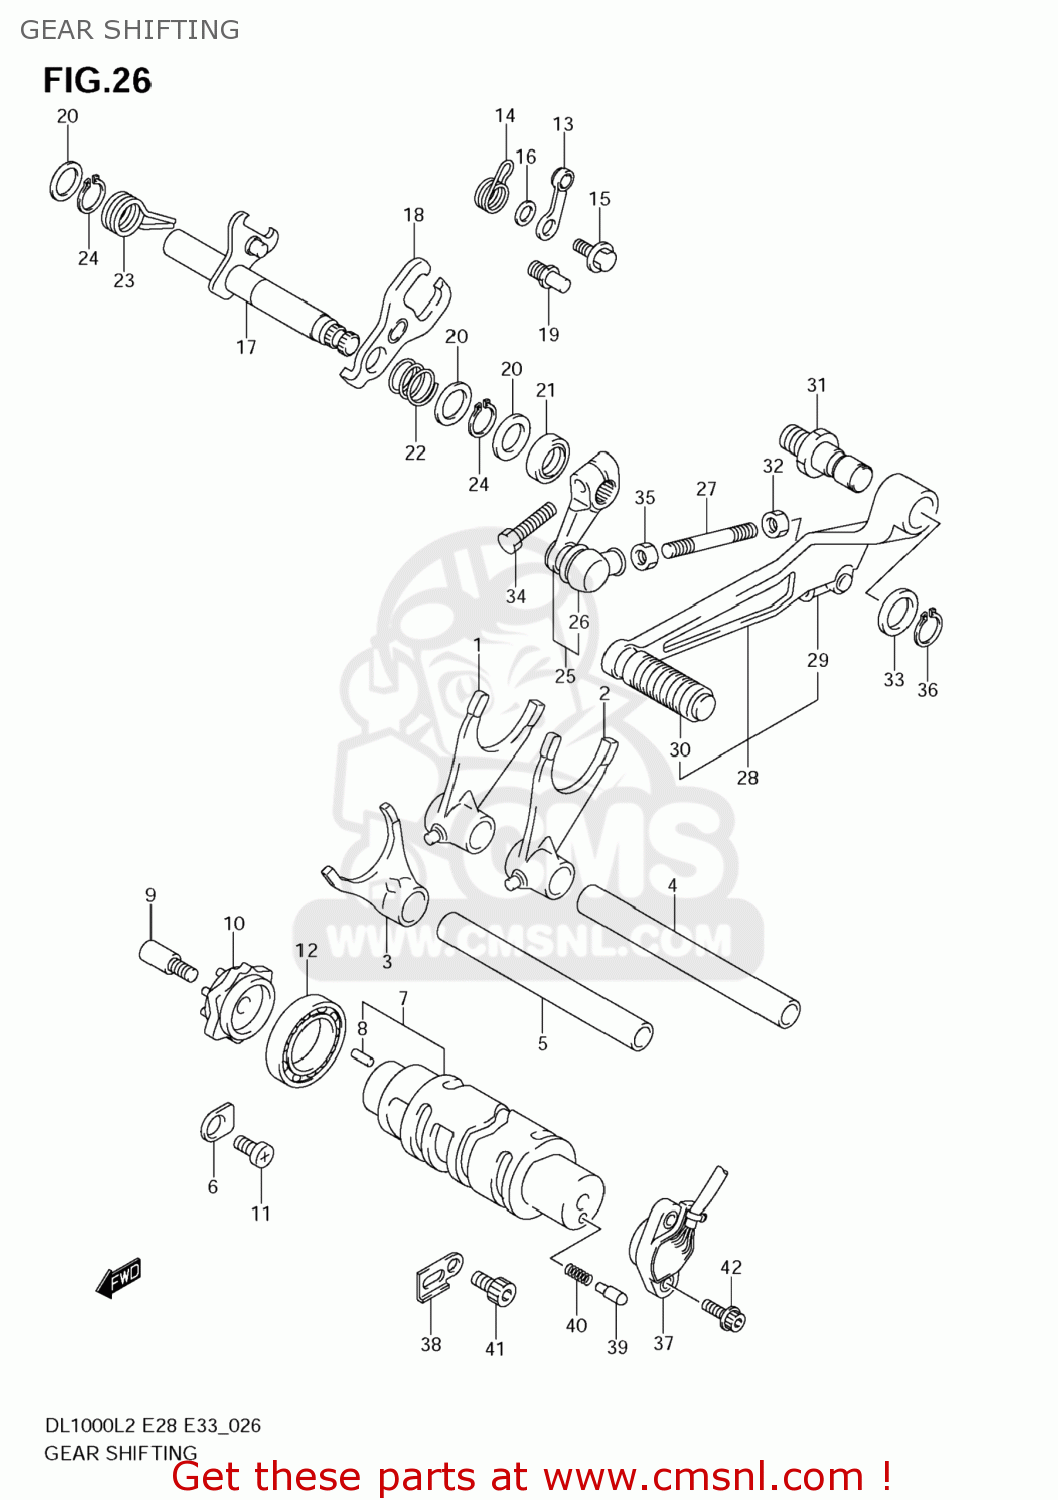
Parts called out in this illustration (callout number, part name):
1	FORK,GEAR SHIFT
2	FORK,GEAR SHIFT NO.1
3	FORK,GEAR SHIFT NO.3
4	SHAFT,GEAR SHIFT FORK
5	SHAFT,GEAR SHIFT FORK
6	RETAINER
7	CAM,GEAR SHIFT
8	PIN
9	PIN,SHIFT CAM DRIVEN GEAR
10	PLATE,GEAR SHIFT CAM
11	SCREW(6X12)
12	BEARING
13	STOPPER,SHIFT CAM
14	SPRING,GEAR SHIFT CAM STOPPER
15	BOLT(6X14.3)
16	WASHER
17	SHAFT,GEAR SHIFT
18	PLATE,GEAR SHIFT CAM DRIVE
19	STOPPER,GEAR SHIFT ARM
20	SHIM(14X22X1)
21	SEAL,OIL(14X22X7.3)
22	SPRING
23	SPRING
24	CIRCLIP
25	ARM,GEAR SHIFT LINK
26	COVER,DUST
27	ROD,GEAR SHIFT LINK
28	LEVER ASSY,GEA
29	COVER,DUST
30	RUBBER,GEAR SHIFT PEDAL
31	SHAFT,GEAR SHIFT LEVER
32	NUT
33	WASHER(12.5X20X1)
34	BOLT
35	NUT
36	CIRCLIP
37	BASE ASSY,GEAR SHIFT TERMINAL
38	CLAMP,GENERATOR LEAD WIRE
39	PIN(5X15.5)
40	SPRING
41	BOLT
42	BOLT
